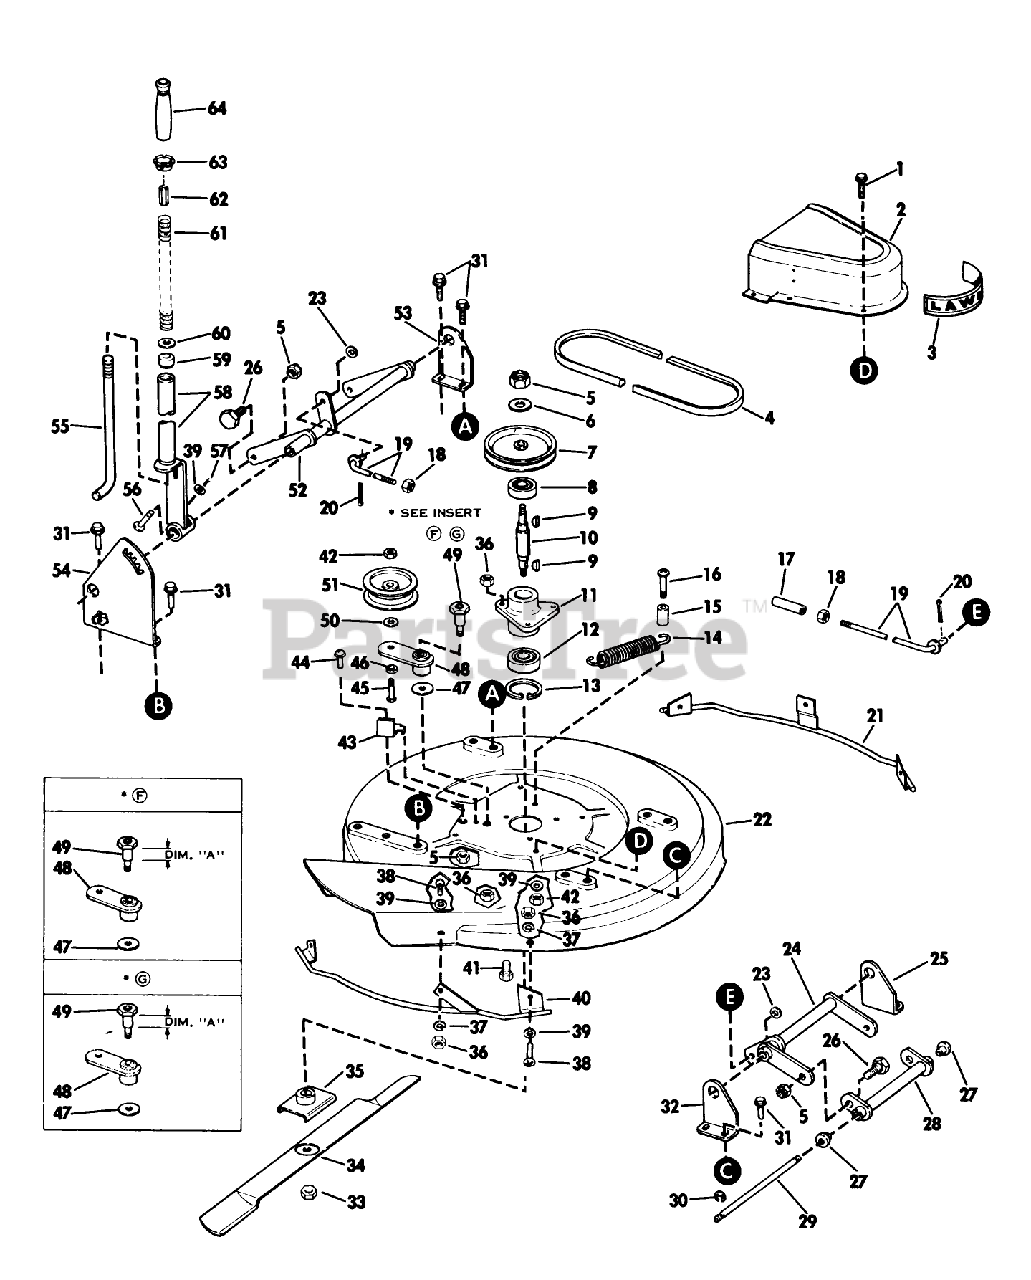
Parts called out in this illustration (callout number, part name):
18	Jam Nut-Stabilizer Link Assembly
22	Housing-Mower 30"
42	LOCKNUT
47	Washer
49	Pin-Idler Arm to Housing
